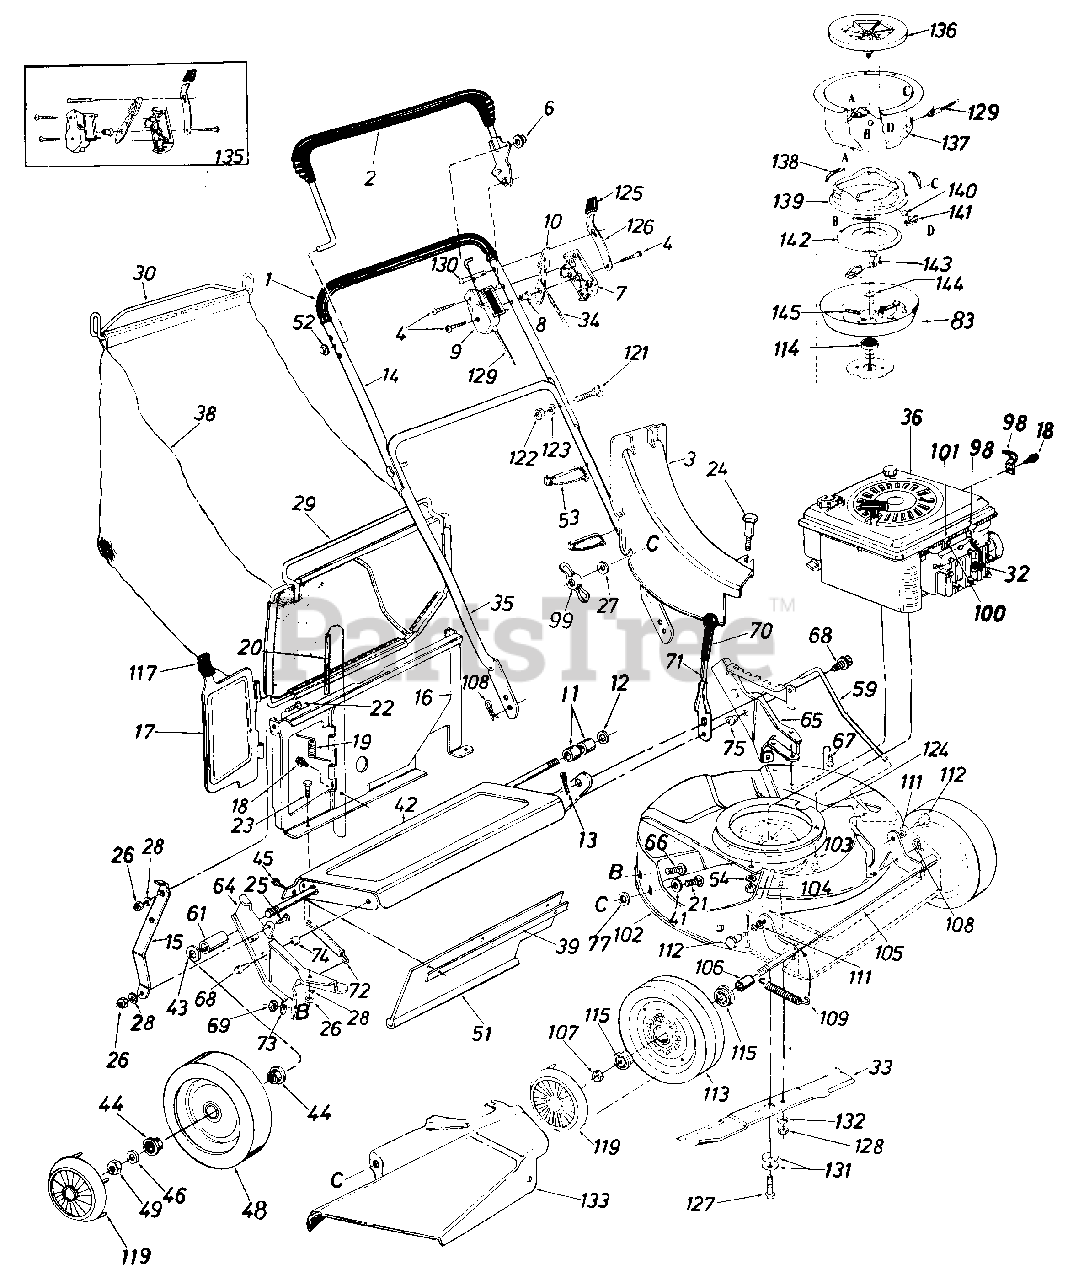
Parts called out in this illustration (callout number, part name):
2	Control Handle Ass'y.-L.H.
3	Top Discharge Chute Ass'y.
4	Truss Mach. Scr. #12 x 1.50" Lg.
6	Push Cap
7	Control Panel Half
8	Control Disc Pin
9	Ciutch Panel Half
10	Throttle Control Lever
11	Spacer .526" I.D. x .690" O.D. x .640" Lg.
12	Fl-Wash. .531" I.D. x .930" O.D.
13	Cotter Pin 3/32" Dia. x.75" Lg.
14	Upper Handle-Chrome
15	Panel Support Brkt.
16	Top Catcher Panel
17	Top Door
18	Hex "B" Tap Scr. #10 x .38" Lg.
19	Torsion Spring .20" I.D. x 1.14" Lg.
20	Pivot Pin .187" Dia. x 7.25" Lg.
21	Carriage Bolt 1/4-20 x .62"
22	Truss Mach. Scr. 1/4-20 x .5" Lg.
23	Hex Bolt 1/4-20 x .50" Lg.*
24	Shld. Bolt .312" Dia. x .18" Lg. Special
25	Truss Mach. Scr. 1/4-20 x .62" Lg.
26	Hex Nut 1/4-20 Thd.
27	Bell-Wash. 1/4" I.D.
28	L-Wash. 1/4" I.D.
29	Front Grass Catcher Frame
30	Grass Catcher Handle
32	Spark Plug Insulator
33	21" Blade
34	Throttle Control Wire 58"
35	Lower Handle-Chrome
36	Engine
38	21" Top Discharge Grass Bag
39	Retaining Strip
41	Fl-Wash. .344" I.D. x .62" O.D.
42	Rear Axle Ass'y.
43	Fl-Wash. .531" I.D. x .930" O.D.
44	Flange Ball Bearing 1/2" I.D.
45	Hex AB-Tap Scr. 1/4 x .62"
46	Fl-Wash. .531" I.D. x .930" O.D.
48	Rear Wheel Ass'y.-Comp. 8 x 1 .75
49	Hex L-Nut 1/2-20 Thd.
51	Rear Flap
52	Push Cap
53	Cable Tie
54	L-Wash 1/4" I.D.
59	Height Adj. Rod
61	Spacer .513" I.D. x .703" O.D. x .690" Lg.
64	R.H. Handle Wheel Brkt. Ass'y.
65	L.H. Handle Wheel Brkt. Ass'y.
66	Carriage Bolt 5/16-18 x .62"
67	Hex Wash. Hd. B-Tap Scr. 5/1 6-1 8
68	Hex Wash. Hd. TT-Tap Scr. 3/8-1 6
69	Hex Nut 5/16-18 Thd.
71	Height Adj. Lever
72	Extension Spring .50" O.D. x 3.80" Lg.
73	Bell-Wash. .345" I.D. x .88" O.D.
74	Spacer .385" I.D. x .502" O.D. x .270" Lg.
75	Shld. Spacer. 500" Dia. x . 1 00
77	Bolt Retainer 1/4 x .50" O.D.
83	Clutch Blade Housing Ass'y.
98	Throttle Control Cable Clip
99	Wing Nut
100	Hex B-Tap Scr. #10 x .62" Lg.
101	Casing Clamp
104	Speed Nut 1/4-20 U-Type
105	Front Axle Ass'y.
106	Sleeve .526" I.D. x .690" O.D. x .880" Lg.
107	Hex L-Nut 1/2-20 Thd.
108	Intern. Cotter Pin 5/16" Dia.
109	Extension Spring .50" O.D. x 3.20" Lg.
111	Intern. L-Wash. 3/8 x .56" O.D.
112	Shld. Bolt .623" Dia. x .425
113	Front-Wheel Ass'y. Comp. 7x 1.75
114	Ball Brg. .669" I.D. x 1.574"
115	Flange Ball Bearing 1/2" I.D.
117	Door Grip x 2.5
119	Hub Cap-Plastic
121	Curved Carr. Bolt 5/16-18 x 1.38" Lg.
122	Hex Nut 5/16-18 Thd.
123	L-Wash. 5/16" I.D.
124	Blade Brake Clutch Comp.
125	Spring Lever Knob
126	Lockout Spring
127	Hex Cent. L-Bolt 3/8-24 x 2.00" (Grade 8)
128	Hex Nut 3/8-24 Thd. (Grade 8)
129	BBC Clutch Cable-46"
130	Lock Pin .314" Dia. x 1.75"
131	Bell-Wash. .400" I.D. x .88" O.D.
132	L-Wash. 3/8" I.D.
133	Side Chute Deflector
135	Kit-Control Housing Comp.
136	Fan Adapter
137	Clutch Housing
138	Extension Spring .35" O.D. x 1.75" Lg.
139	Brake Cup Cone
140	Steel Ball .500" Dia.
141	Ball Block
142	Clutching Cone
143	Hex Tap L-Scr. 1/4-20 x .75"
144	Fl-Wash. .690" I.D. x 1.060" O.D.
145	Compression Spring .35" O.D. x 2.00" Lg.
